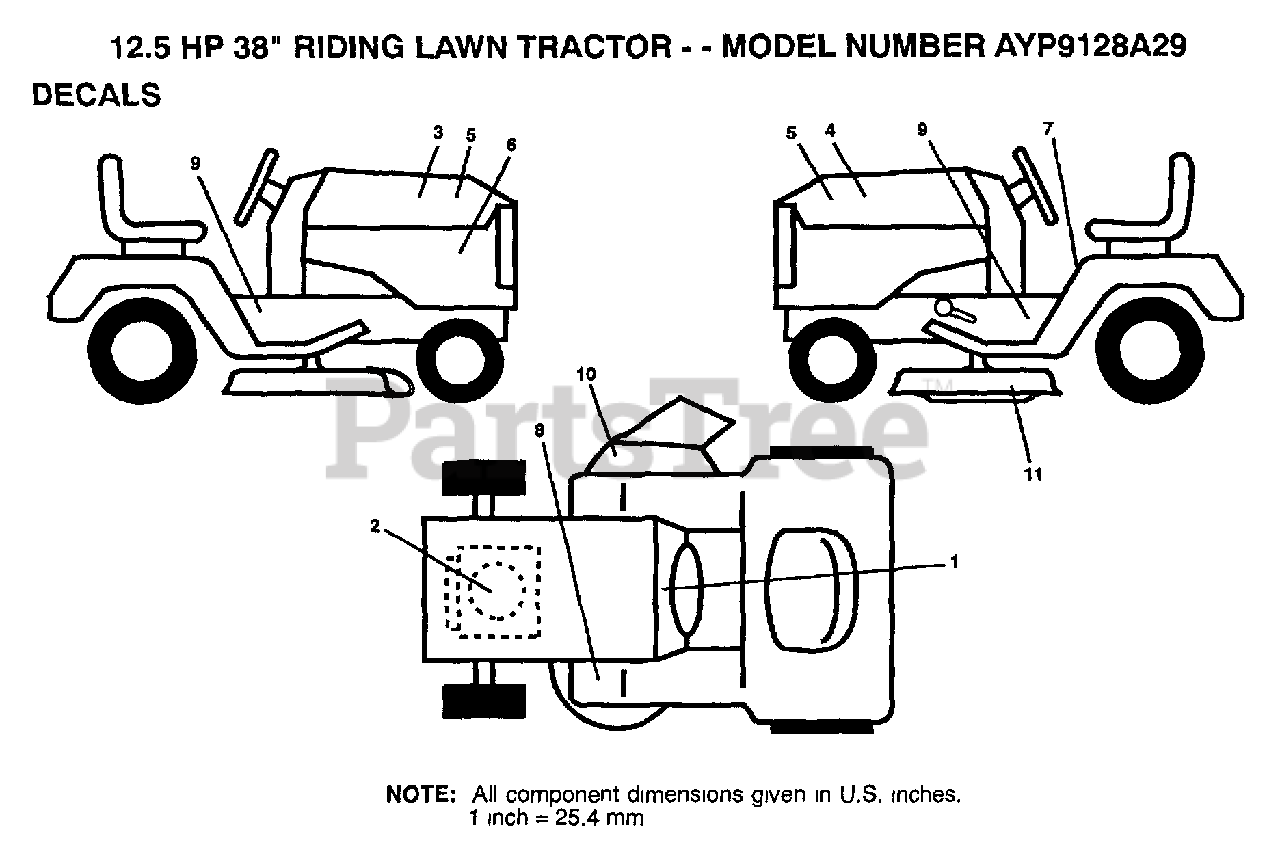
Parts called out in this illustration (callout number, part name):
7	DECAL
10	DECAL WARING
11	DECAL INSTRUCTION CAUTION
